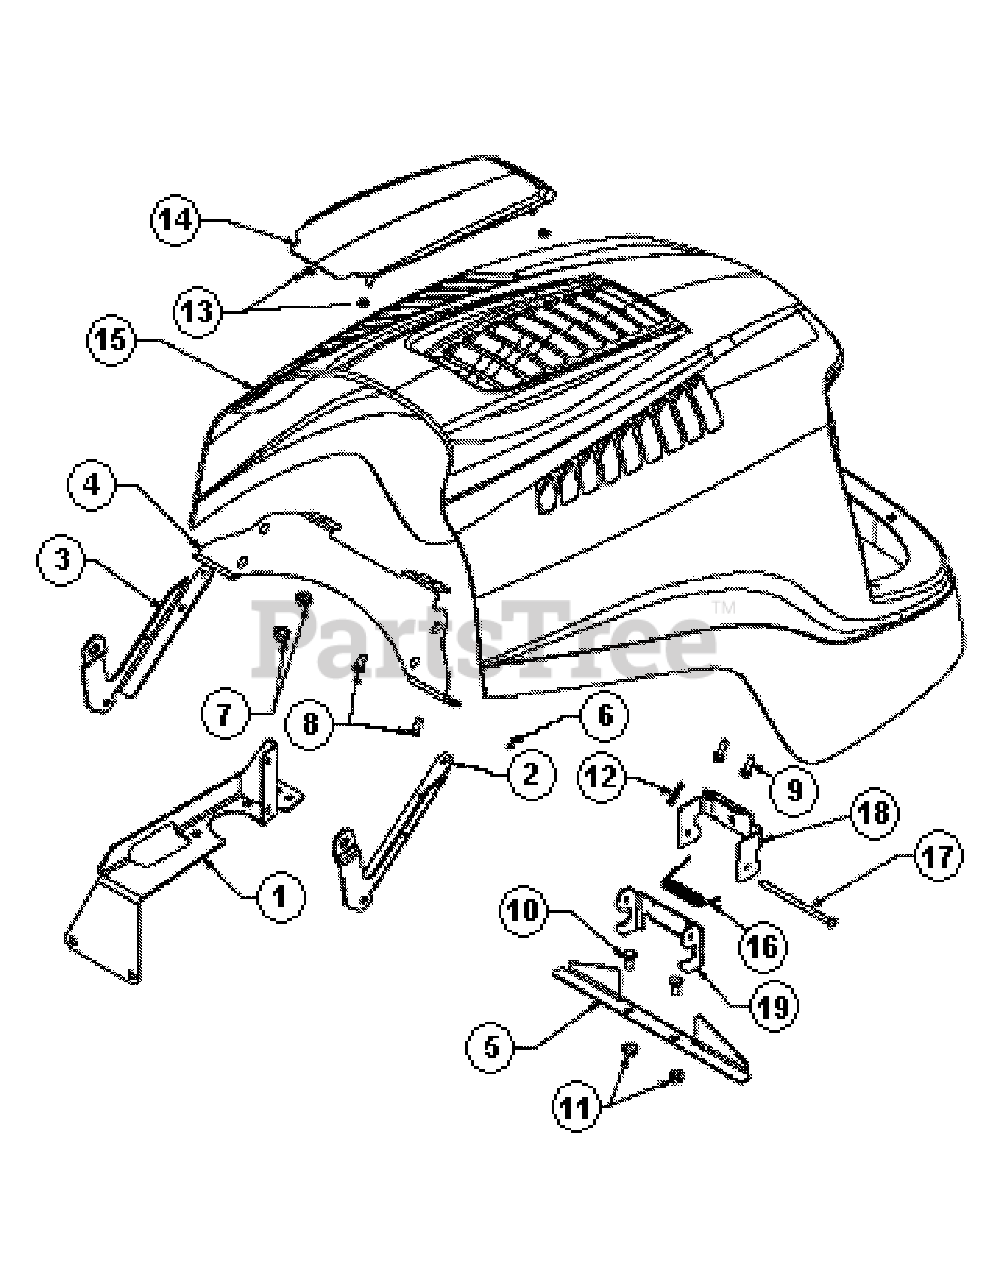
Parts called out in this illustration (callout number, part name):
6	#10-16 x .500 Hex Screw
7	5/16-18 x .50 Screw
8	5/16 x .75 HiLow Screws
9	1/4-20 x .750 Screw
10	5/16-18 x .625 Bolt
11	5/16-18 Nylon Flange Lock Nut
12	Cotter Pin
14	Hood Cover
15	Hood
16	Latch Spring
18	Latch Plate
19	Pivot Latch Bracket
